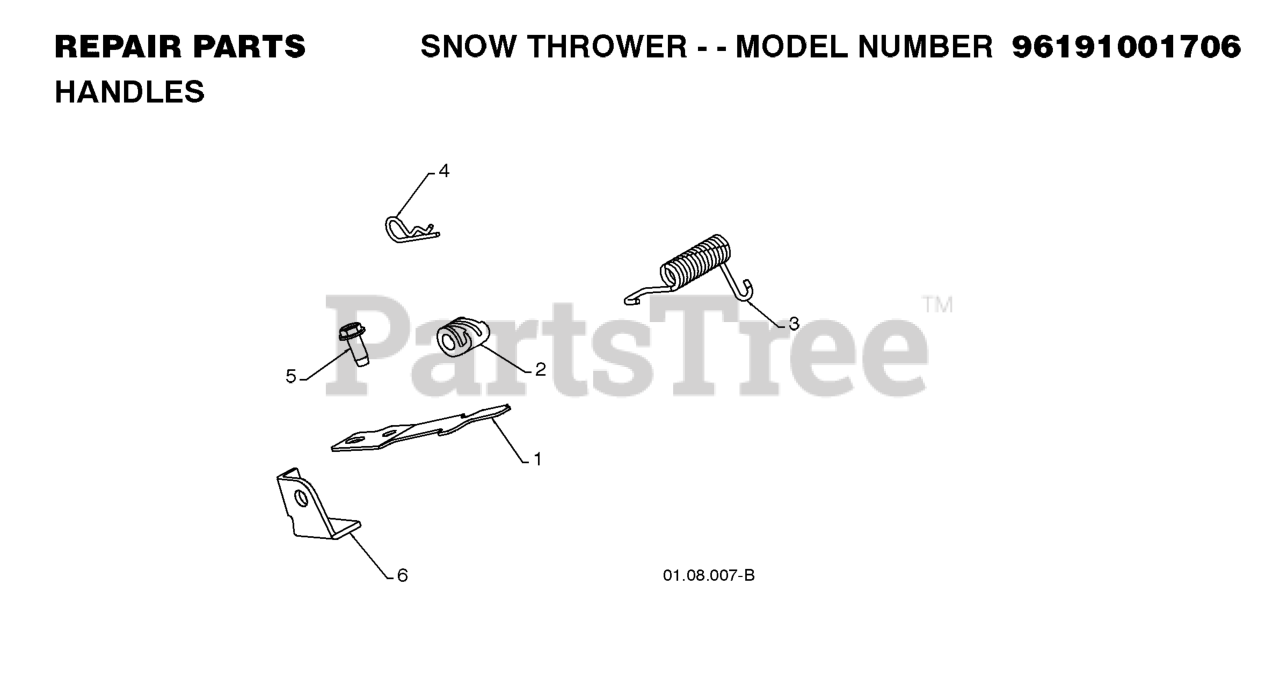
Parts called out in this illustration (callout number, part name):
1	SPRING.INTERLOCK
2	CAM.INTERLOCK.RELEASE
3	RP SPRING, TORSION
4	SPRING RETAINER
5	SCREW 14-20 X 5/8
6	STOP.INTERTLOCK
